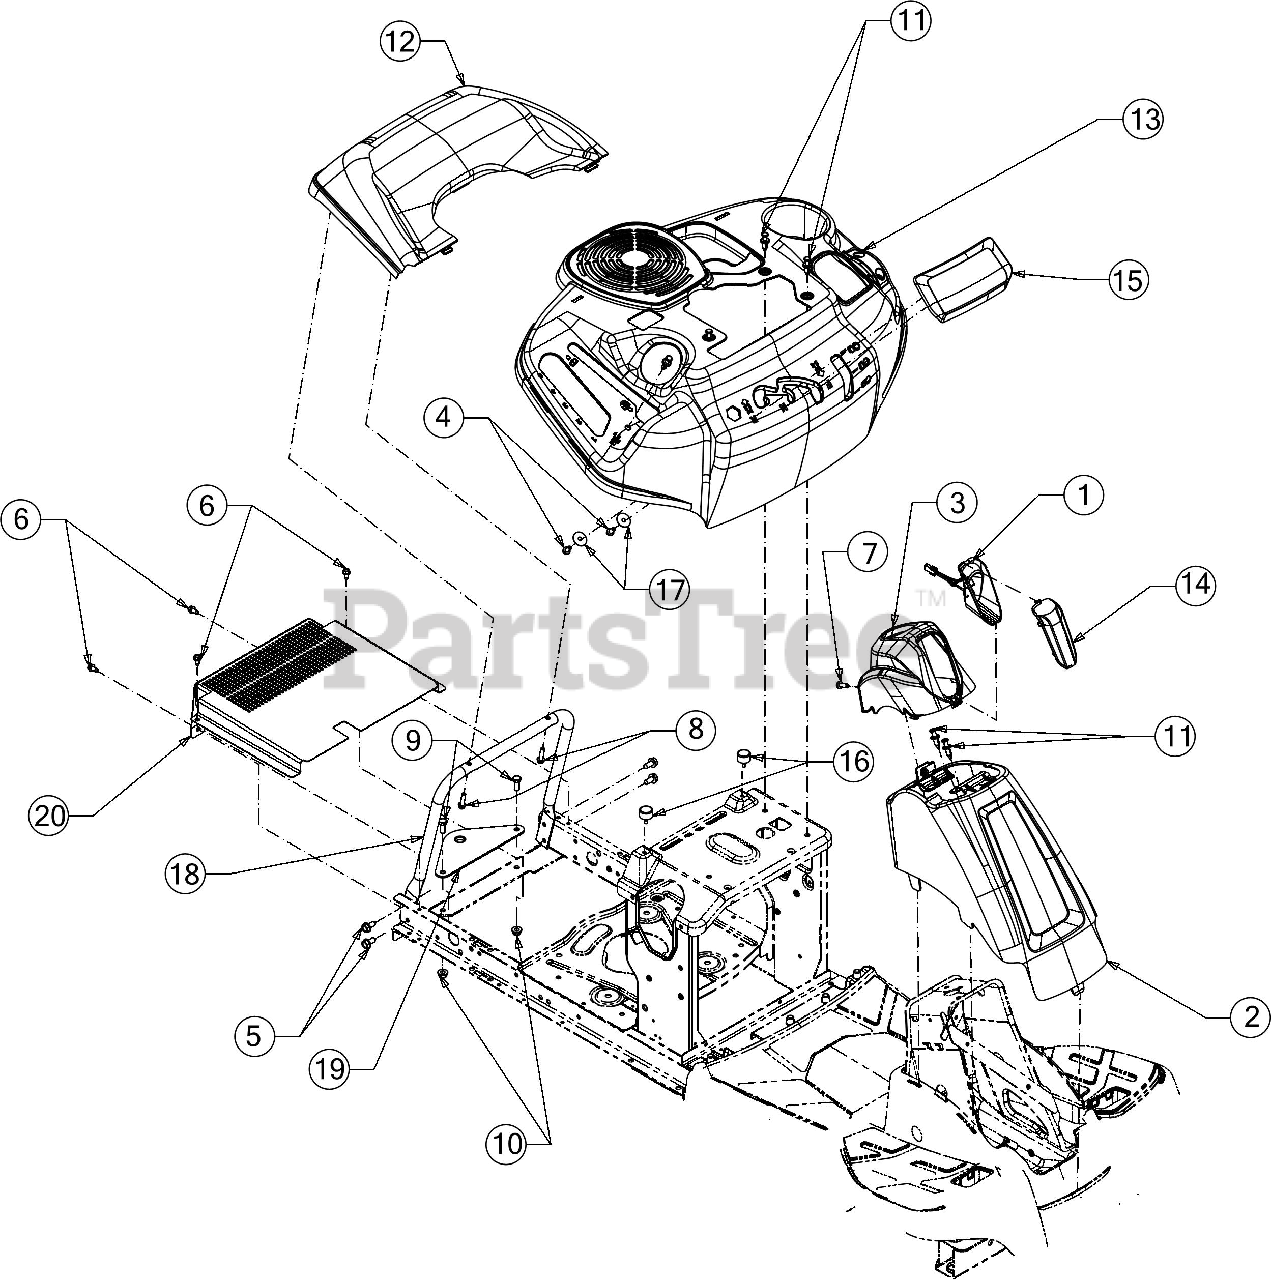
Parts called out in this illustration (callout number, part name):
1	HEADLIGHT HARNESS ASSEMBLY
2	COLUMN COVER ASSEMBLY (MTD RED)
3	STEERING COLUMN CAP (MTD RED)
4	HEX SCREW 1/4-15 x .50
5	SCREW 5/16-18 x .750
6	SCREW 1/4-20 X.500
7	SCREW 1/4-20X.75
8	SCREW 1/4-15 x 1.00
9	SCREW 5/16-18 x .75 GR5
10	FLANGE LOCK NUT 5/16-18
11	PLASTIC RIVET
13	FENDER
14	LED HEADLIGHT LENS
15	FENDER COVER
16	BUMPER .62 DIA x .50
17	FLAT WASHER
18	REAR SUPPORT TUBE
19	HITCH PLATE
20	HYDRO COVER HEAT SHIELD (B&S)
